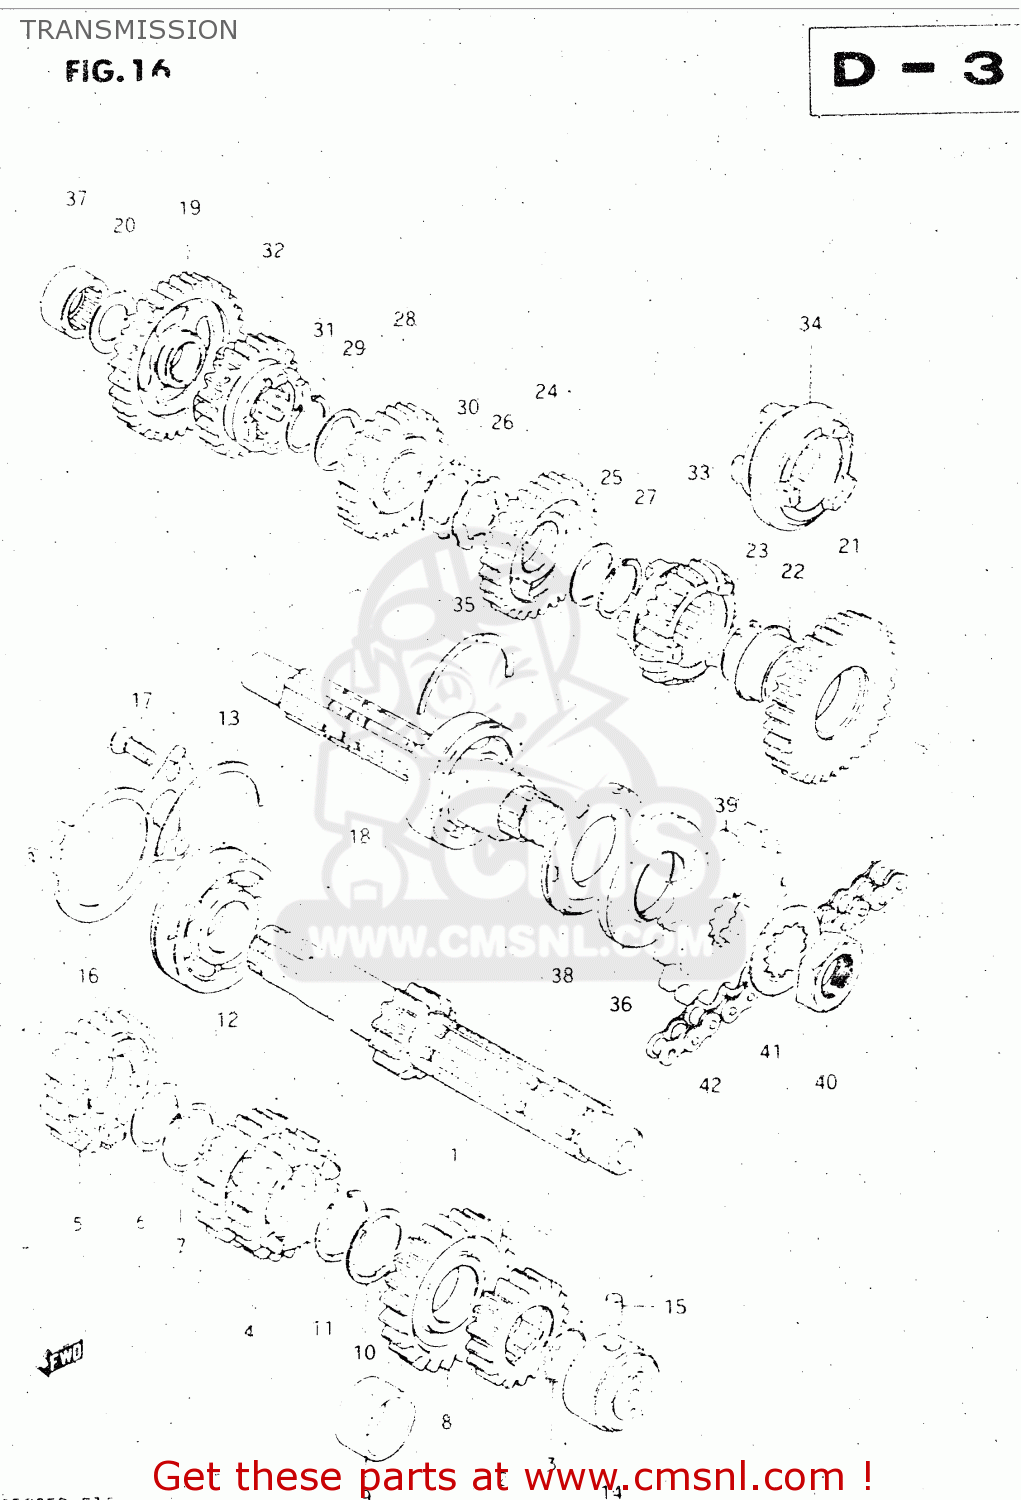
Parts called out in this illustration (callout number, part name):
1	SHAFT,COUNTER
2	GEAR,SECOND DRIVE
3	RING,SNAP
4	GEAR,THIRD DRIVE
5	GEAR,FIFTH DRIVE
6	WASHER
7	CIRCLIP
8	GEAR,SIXTH DRIVE
9	SPACER(25X30.5X12.5)
10	WASHER,LOCK
11	CIRCLIP
12	BEARING(25X62X17)
13	C-RING
14	BEARING
15	PIN
16	PLATE,COUNTERSHAFT BEARING
17	SCREW
18	SHAFT,DRIVE
19	GEAR,FIRST DRIVEN
20	WASHER
21	GEAR,SECOND DRIVEN
22	BUSHING
23	CIRCLIP
24	GEAR,THIRD DRIVEN
25	WASHER,LOCK
26	WASHER,LOCK
27	CIRCLIP
28	GEAR,FOURTH DRIVEN
29	WASHER,LOCK
30	WASHER
31	CIRCLIP
32	GEAR,FIFTH DRIVEN
33	GEAR,SIXTH DRIVEN
34	WHEEL, SLIDING
35	C-RING
36	SEAL,OIL(32X62X7)
37	ROLLER BEARING (20X34X1
38	SEAL,OIL(32X62X5.5)
39	SPROCKET,ENGINE
40	NUT
41	WASHER
42	CHAIN ASSEMBLY,DRIVE
